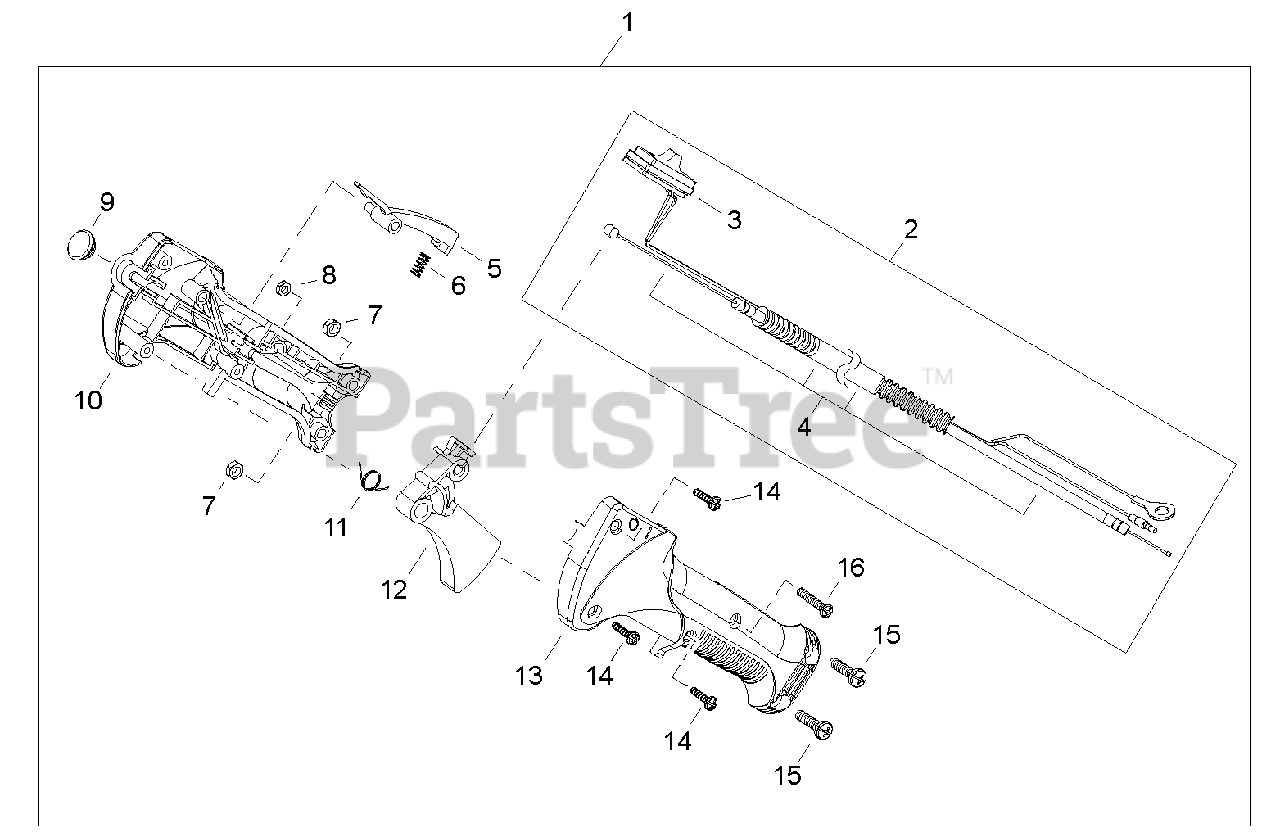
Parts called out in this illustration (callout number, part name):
1	THROTTLE CONTROL ASSY
2	THROTTLE CONTROL ASSY
3	SWITCH, IGNITION
4	CABLE, THROTTLE
5	LEVER, TRIGGER LOCKOUT
6	SPRING
7	NUT - 5
8	NUT - 4
9	PLUG
10	HANDLE, CONTROL - RIGHT
11	SPRING
12	TRIGGER, THROTTLE
13	HANDLE, CONTROL - LEFT
14	SCREW - 4X16 -- TAPPING
15	SCREW - 5X20
16	SCREW - 4X23
